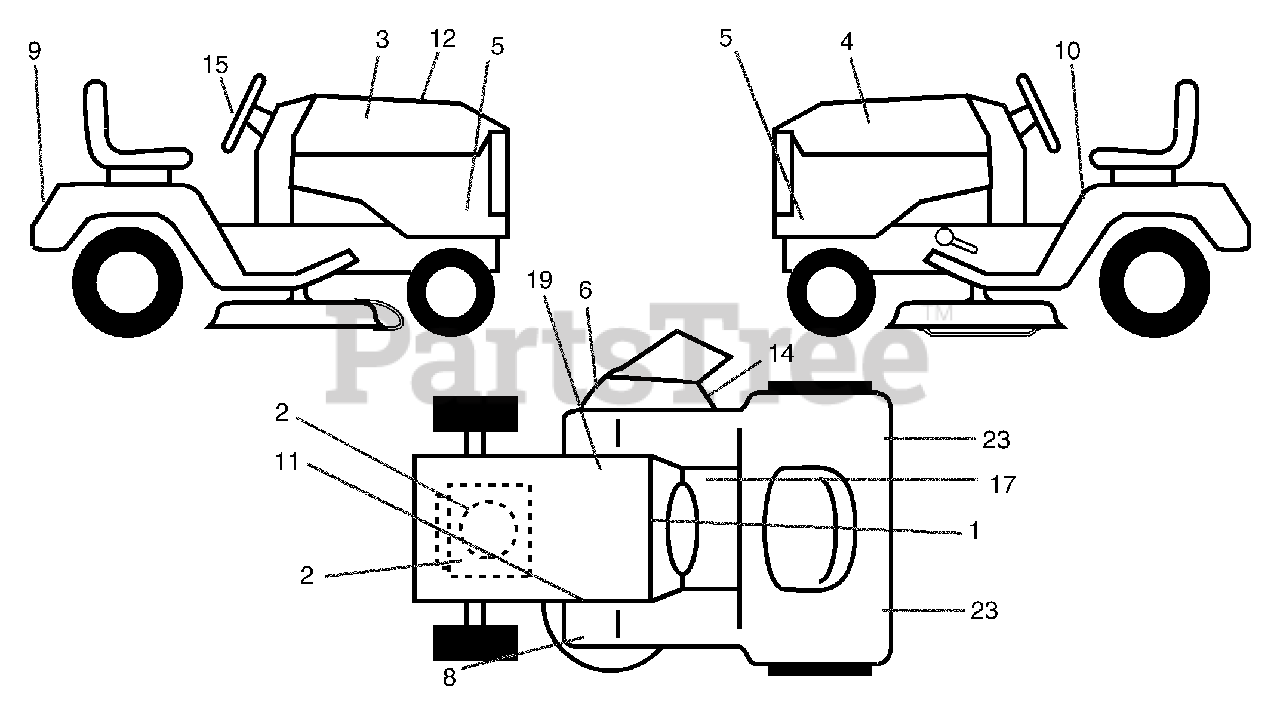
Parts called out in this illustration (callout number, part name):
1	Decal, Dash
2	Decal, Engine
3	Decal, Hood, RH
4	Decal, Hood, LH
5	Decal, Hood Sides
6	Decal, Warning
8	Decal, Deck Caution
9	Decal
10	Decal, Danger
11	Ft. Rest
12	Decal, Repl.
14	Decal, V-Belt Schematic
15	Decal, Ins. Whl. Strg.
17	Decal, Saddle Brake Parking
19	Decal, Battery
23	Reflector, Taillight
